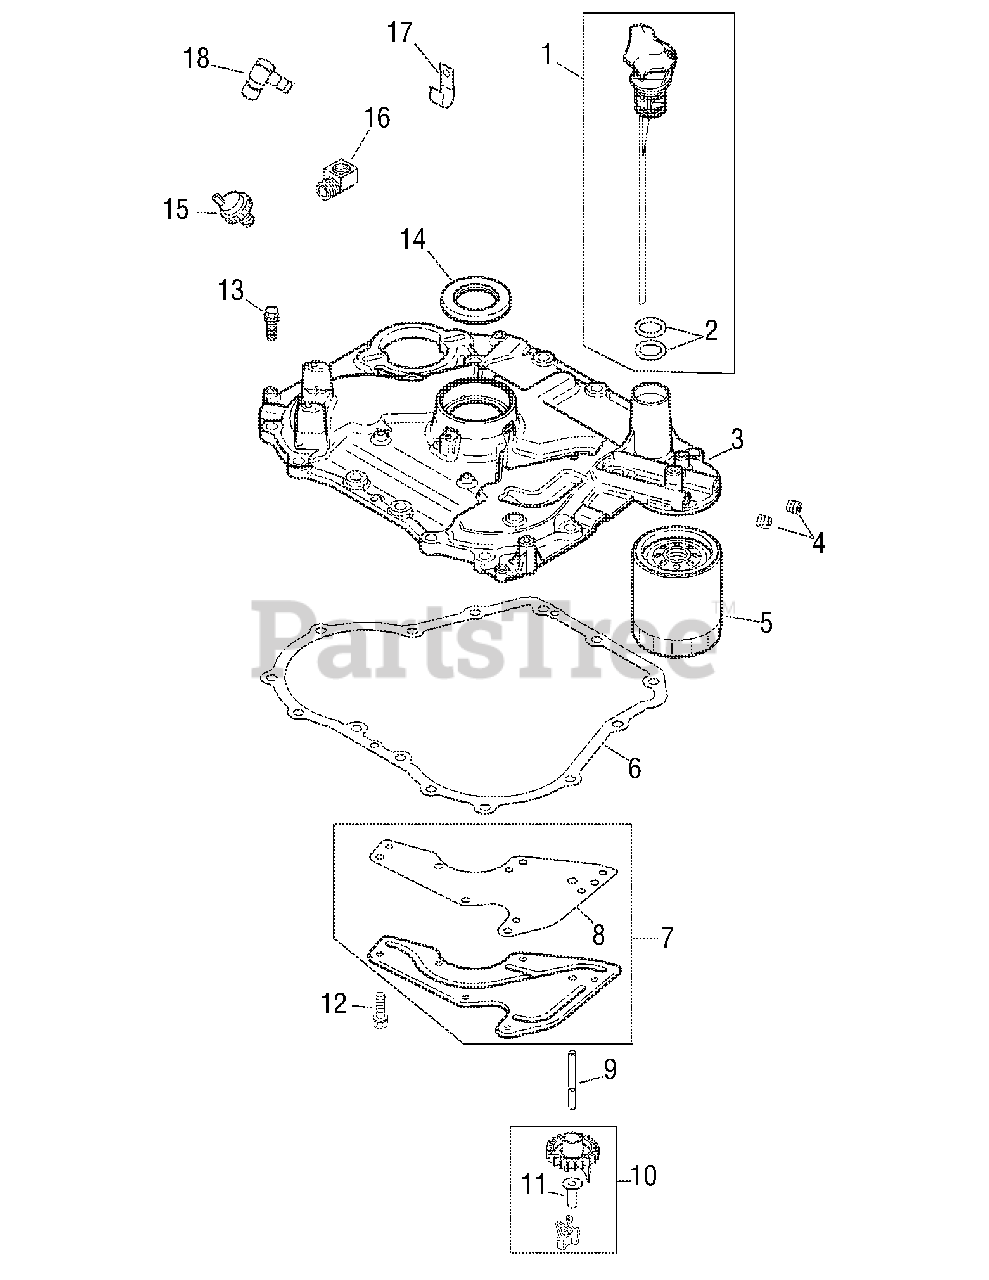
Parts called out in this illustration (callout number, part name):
1	Kit, dipstick assembly (Includes 2)
2	O-Ring, dipstick
3	Plate assembly, closure (Includes 4,10,11)
5	Filter, oil
6	Gasket, closure plate
7	Kit, oil passage cover (Includes 8)
8	Gasket, oil passage
9	Shaft, governor gear
10	Kit, gear and weight assembly (Includes 11)
11	Pin, governor regulating
12	Screw, hex. flange M5x0.8x13
13	Screw, hex. flange M8x1.25x30
14	Seal, oil
15	Switch, pressure
16	Elbow, street
17	Clip, cable
18	Connector, 90°
